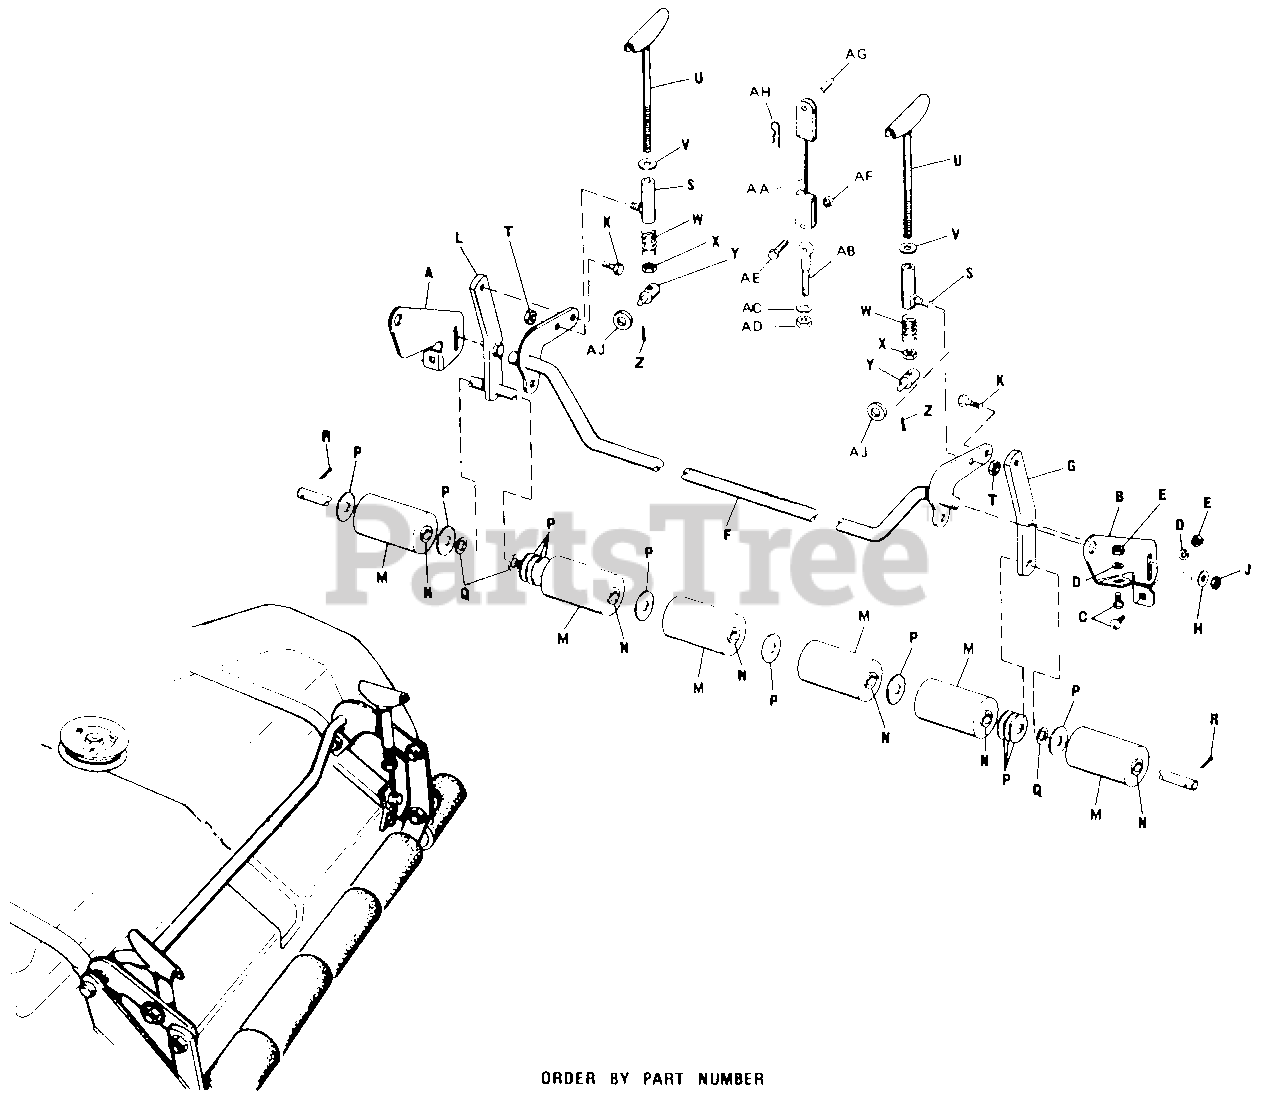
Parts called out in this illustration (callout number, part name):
A	R.H. Roller Bracket
B	L.H. Roller Bracket
C	Carriage Bolt, 3/8"-16 x 3/4"
D	Lock Washer 3/8"
E	Full Hex. Nut, 3/8"-16
F	Rocker Assembly Arm
G	Roller Bar Assembly L.H.
H	Plain Washer, 3/8"
J	Full Hex. Nut, 3/8"-16
K	Hex. Cap Screw, 3/8"-16 x 1"
L	Roller Shaft Assembly
M	Roller W/Bushing
R	Cotter Pin, 3/16"-1"
S	Socket Crank Assembly
T	Full Hex. Nut, 3/16"-16
U	Adjusting Screw Assembly
V	Plain Washer 3/8"
W	Adjusting Screw Spring
X	Hex. Jam Nut, 3/8"-16
Z	Cotter Pin, 3/32" x 3/4"
AA	Cable Assembly, Lift
AC	Washer, Lock, 3/8" Std.
AD	Nut, Hex, Full, 3/8"-16 NC
AE	Screw, Cap, Hex, 3/8"-16 x 1" lg.
AF	Nut, Hex, Full, Lock, 3/8"-16 NC
AG	Pin
AH	Clip, Spring
AJ	Plain Washer, 5/16"
